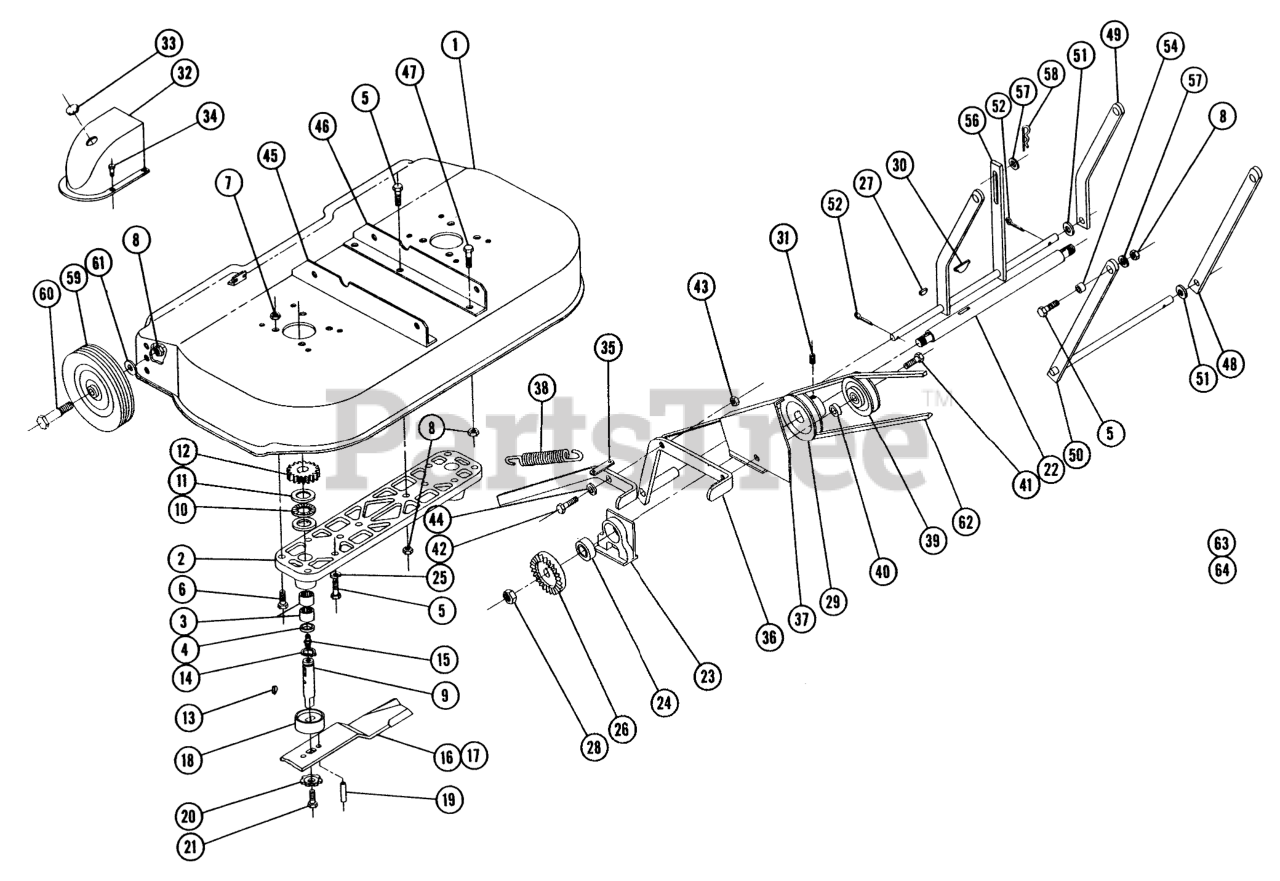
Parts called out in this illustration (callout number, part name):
1	Ass-y. Deck
5	Bolt 3/8-16 x 1
6	Bolt 5/16-18 x
7	Nut-Nylok
8	3/8-16 E.S.
11	WASHER-THRUST
19	SPIROL ROLL PIN
21	Bolt 3/8-16 x 7/8
23	BEARING SUPPORT
25	Lockwasher
27	Key #5 Woodruff
28	Nut Hex 5/8-18 Thin
31	Set Screw 5/16-18 x 5/16
33	PLUG BUTTON
34	SCREW
36	59027 1969 OPC
41	Bolt 3/8-16 x 7/8
42	Bolt-Hex 1/4-20
43	Nut-Nylok
44	Washer
45	Bracket Mtg. R.H.
46	Bracket Mtg. L.H.
47	Bolt 3/8-16 x 3/4
48	Link-Front
51	Washer
52	Cotter Pin
55	3/8-16 E.S.
56	Bar Lift
57	Washer
58	Hairpin
60	BOLT-SHOULDER
61	Washer 3/8
63	Decal
